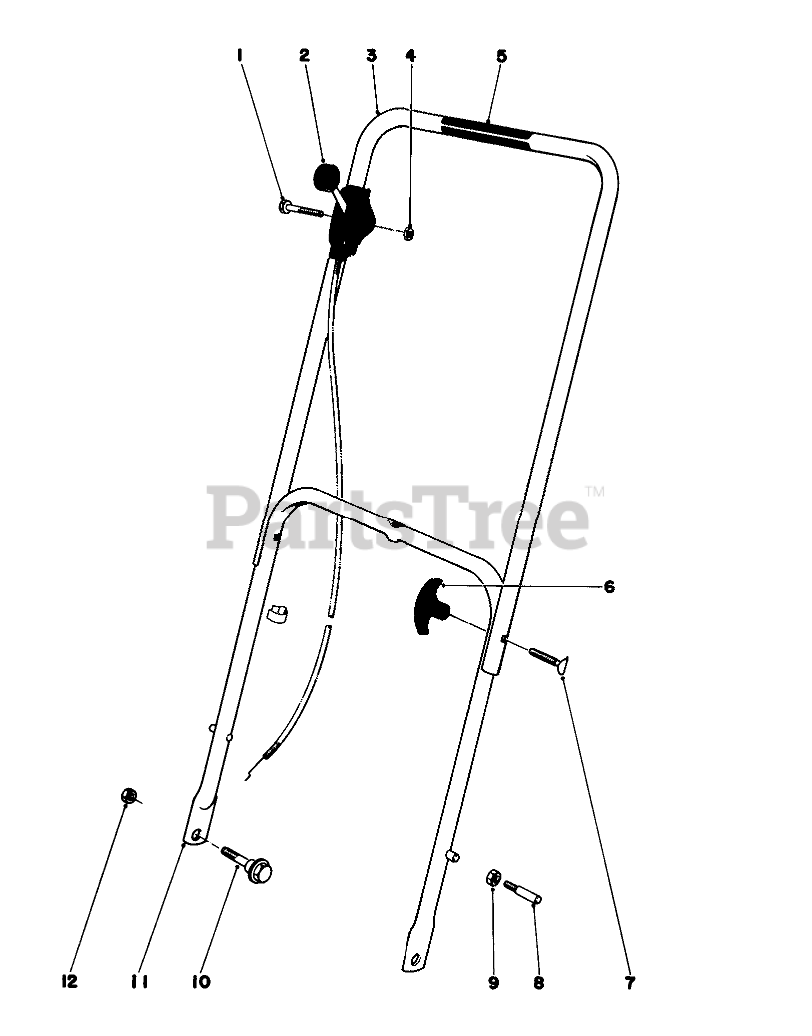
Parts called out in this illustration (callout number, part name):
1	SCREW-HH
2	Throttle Control
3	Upper Handle
4	NUT-LOCK
5	Decal
7	HANDLE SCREW
8	HANDLE PIN
9	Nut
10	SCREW-SHOULDER
11	19 LOWER HANDLE ASM
12	Nut
13	BOWDEN CLIP
